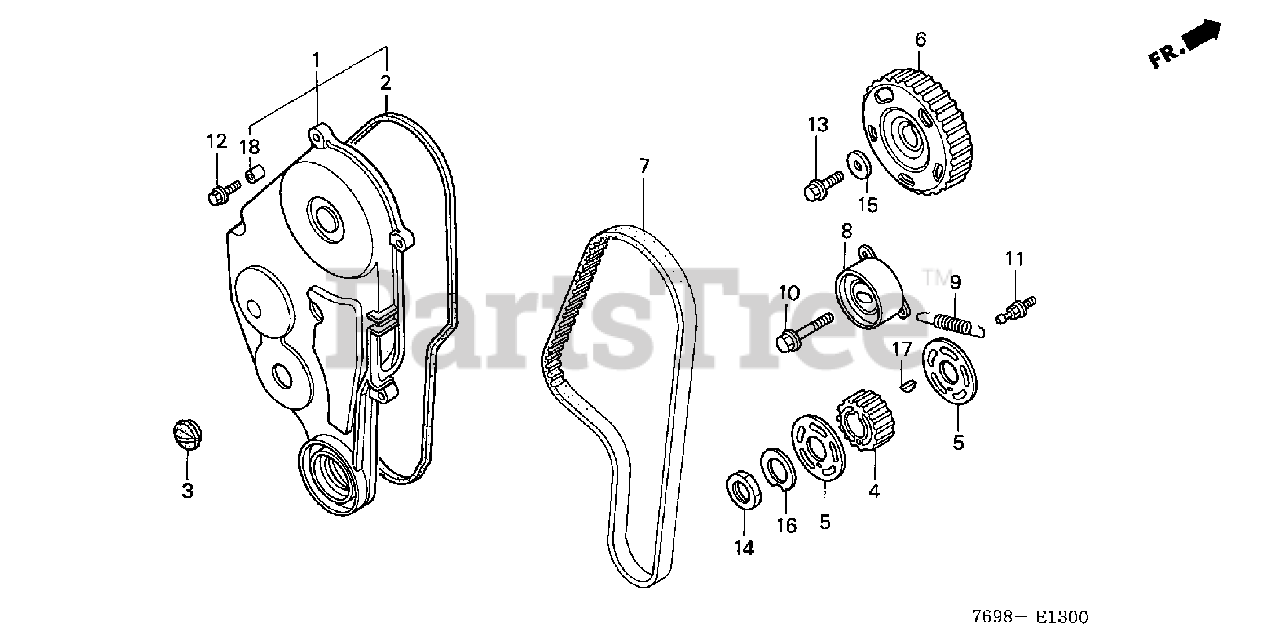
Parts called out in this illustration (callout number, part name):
1	COVER, TIMING BELT
2	GASKET, TIMING BELT COVER
3	GROMMET, TIMING BELT COVER
4	PULLEY, TIMING BELT DRIVE
5	PLATE, TIMING BELT GUIDE
6	PULLEY, TIMING BELT DRIVEN
7	BELT, TIMING
8	TENSIONER, TIMING BELT
9	SPRING, TIMING BELT ADJUSTING
10	BOLT A, TENSIONER
11	BOLT, TIMING BELT ADJUSTER SPRING (NAGOYA RASHI)
12	BOLT, FLANGE (6X20) (CT200)
13	BOLT, FLANGE (8X22)
14	NUT, LOCK (27MM)
15	WASHER, SPECIAL (28X8.5X4.0)
16	WASHER, LOCK (6MM)
17	KEY, SPECIAL (16X15)
18	COLLAR, CONTROL LEVER
